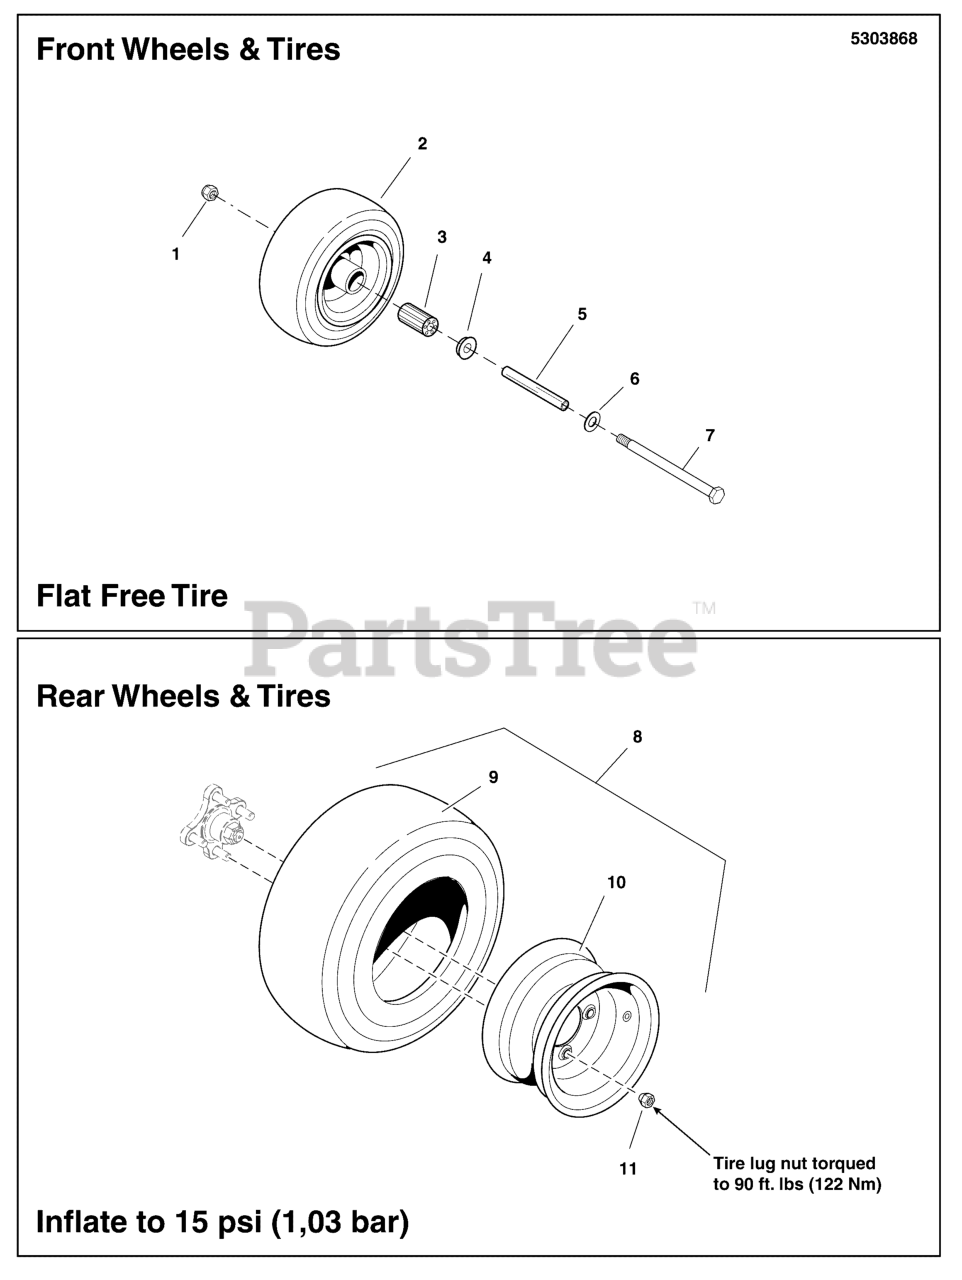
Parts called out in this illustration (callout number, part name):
1	NUT, Hex Flange, Nylock, 1/2-13
2	TIRE ASSM, 9 X 3.5 - 4, FF / CB
3	BEARING, ROLLER 3/4" ID X 3.25" (ONE PER TIRE)(SV)
4	RETAINER, BEARING
5	AXLE, CASTER WHEEL
6	WASHER, 1/2 SAE
7	BOLT, 1/2-13 X 6 GD5 CZ
8	TIRE ASSM, 20 X 7 - 10, TURF, 4 BOLT
9	TIRE, 20X7.00-10NHS, TURF MASTER
10	WHEEL, 10 X 6.00 4/4 SOLID, F237
11	NUT, 1/2-20, FOR WHEEL BOLT SILVER
